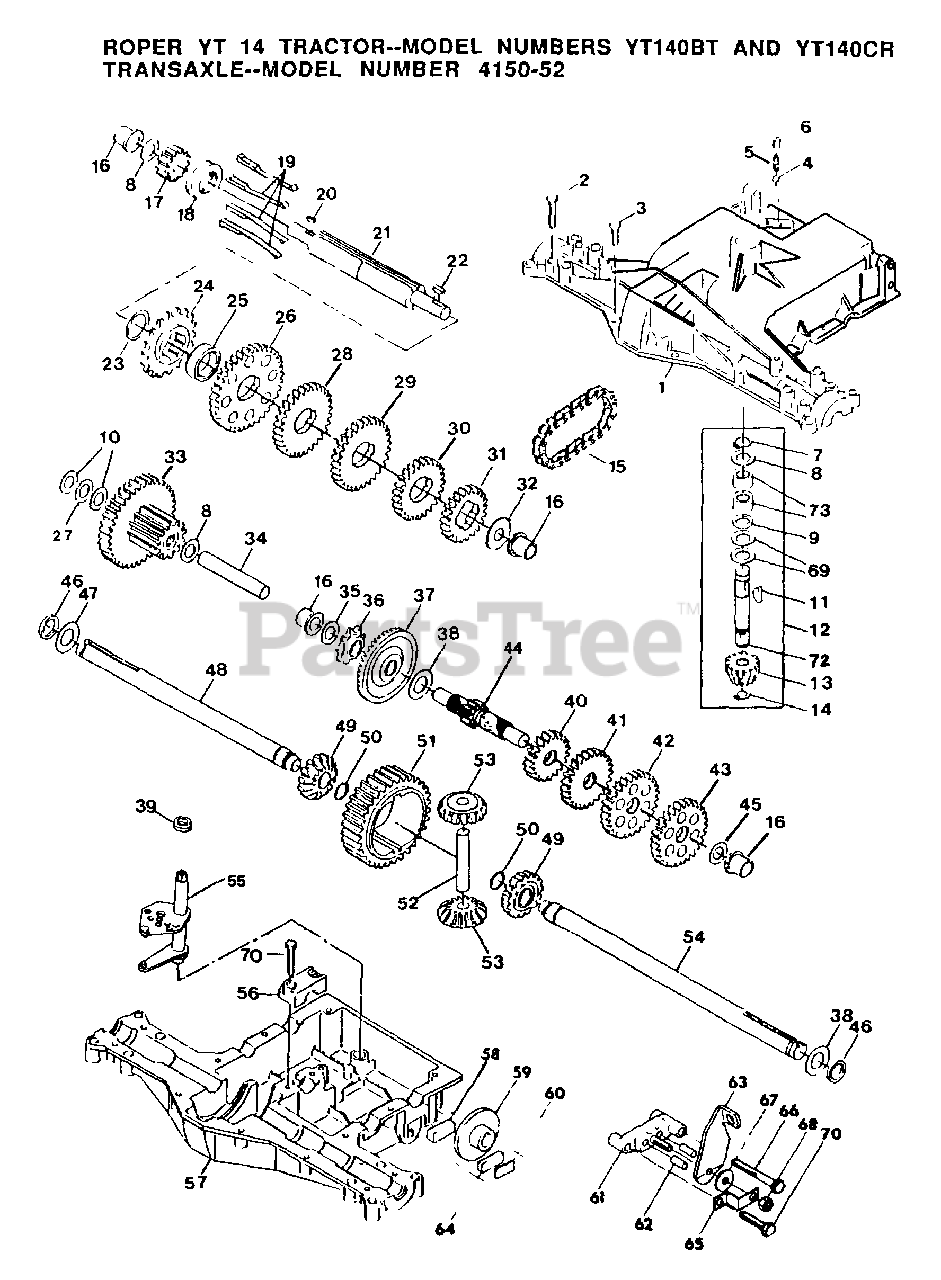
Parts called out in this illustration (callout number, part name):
1	HOUSING, UPPER
2	SCREW 1/4-20 X 1.31
3	SCREW 1/4-20 X .875
4	BALL DETENT
5	SPRING, DETENT
6	SCREW, SET
7	RING RETAINING
8	WASHER PLAIN
8	WASHER, PLAIN .632 X 1.00 X .026
8	WASHER, PLAIN .632 X 1.00 X .060
10	WASHER PLAIN
11	KEY WOODRUFF #9
12	ASSY KIT INPUT SHAFT
13	PINION BEVEL 14 TEETH
14	RING, RETAINING
15	CHAIN, 24 PITCHES
16	BEARING, FLANGE
17	GEAR, SPUR 14T
18	COLLAR CLUTCH
19	KEY, CLUTCH
20	KEY WOODRUFF #3
21	SHAFT, INTERMEDIATE
22	KEY, WOODRUFF, #61
23	RING, RETAINING
24	SPROCKET, 18T
26	GEAR, SPUR 40T
27	SPACER .630 X 1.00 X .169
28	GEAR, SPUR, 35 TEETH
29	GEAR, SPUR, 30 TEETH
30	GEAR, SPUR, 25 TEETH
32	WASHER, PLAIN .640 X 1.37 X .061
33	ASSY, GEAR, COMB., 12T & 35T
34	SHAFT, IDLER
35	WASHER PLAIN
36	SPROCKET, 9 TEETH
37	GEAR, BEVEL, 42 TEETH
38	WASHER PLAIN
38	WASHER, PLAIN .758 X 1.25 X .031
40	GEAR SPUR, 15 TEETH
41	GEAR, SPUR, 20 TEETH
42	GEAR, SPUR, 25 TEETH
43	GEAR, SPUR, 31 TEETH
44	SHAFT, DRIVE
45	WASHER, PLAIN .632 X 1.00 X .060
47	WASHER, PLAIN .758 X 1.25 X .031
49	GEAR MITER 15 TEETH
50	RING, RETAINING
51	GEAR, SPUR, 32 TEETH
52	SHAFT, CROSS
53	GEAR, MITER, 15 TEETH
55	ASSY, SHIFTER & SEAL
56	CAP, SUPPORT
57	PUCK, FRICTION
58	PUCK, FRICTION
59	DISC, BRAKE
61	No Desciption for Part
62	PIN, DOWEL
63	LEVER, ACTUATING
64	PUCK, FRICTION
65	BRACKET, ANTI-ROTATION
67	WASHER, PLAIN .321 X 1.00 X .055
68	LOCKNUT 5/16-24
69	WASHER, PLAIN .632 X 1.38 X .046
70	SCREW TAPPING
